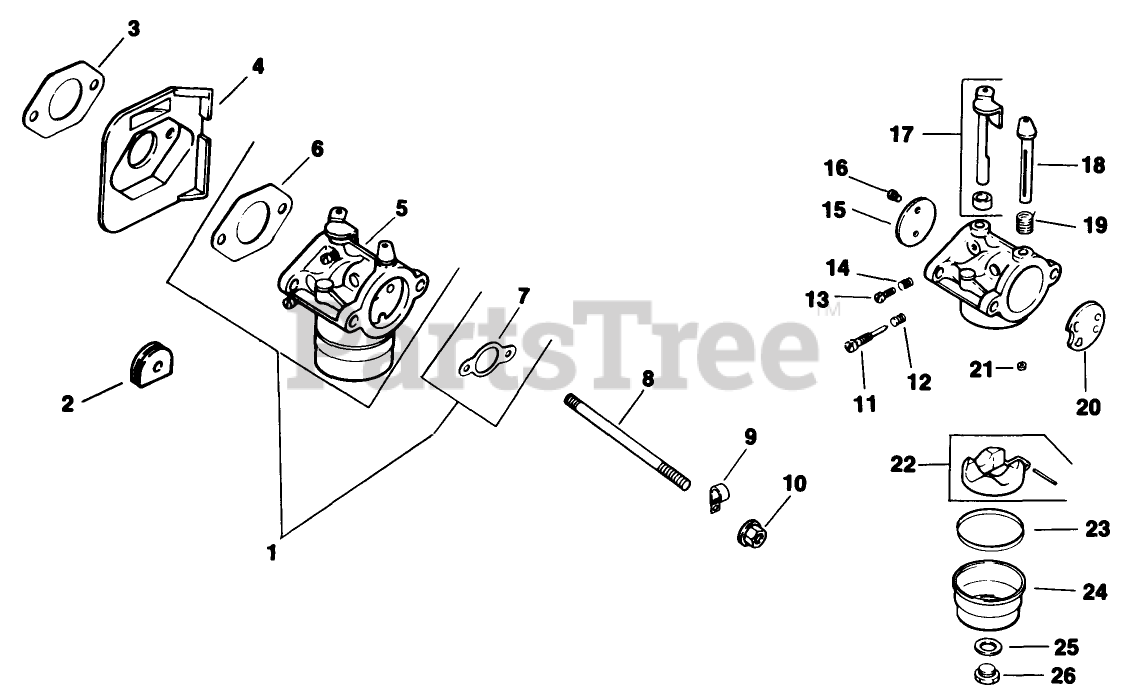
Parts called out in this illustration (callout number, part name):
1	Kit-Carburetor (Incl Ref. #5-7)
2	Grommet (Only On: 72042, 72063, 72062, 72043)
3	Gasket-Carburetor (Only On: 72042, 72063, 72062, 72043)
4	Deflector-Heat
5	Carburetor Assembly (Incl Ref. #11-26)
6	Gasket-Carburetor (Only On: 72042, 72063, 72062, 72043)
7	Gasket-Air Cleaner (Only On: 72042, 72043, 72062, 72063)
8	Stud M6x1.0x110 (Only On: 72042,72043,72062,72063)
9	Clip-Cable (Only On: 72103)
11	Needle-Idle Fuel Adjust (Only On: 72042, 72063, 72062, 72043)
12	Spring-Idle Fuel (Only On: 72042, 72063, 72062, 72043)
13	Screw-Idle Speed Adjust (Only On: 72042,72043,72062,72063)
14	Spring-Idle Fuel (Only On: 72042, 72063, 72062, 72043)
15	Plate-Throttle (Only On: 72042,72043,72062,72063)
16	Screw-Throttle Plate (Only On: 72042,72043,72062,72063)
17	Shaft-W/Lever Seal (Only On: 72042, 72063, 72062, 72043)
18	Shaft-Choke (Only On: 72042. 72063, 72062, 72043)
19	Spring-Choke Return (Only On: 72042,72063, 72062, 72043)
20	Plate-Choke (Only On: 72042, 72063, 72062, 72043)
21	Jet-Main
22	Kit-Float (Only On: 72042,72043,72062,72063)
23	Gasket-Bowl (Only On: 72042,72043,72062,72063)
24	Bowl-Fuel (Only On: 72042, 72063, 72062, 72043)
25	Gasket-Bowl Screw (Only On: 72042, 72063, 72062, 72043)
26	Screw-Fuel Bowl (Only On: 72042, 72063,72062, 72043)
